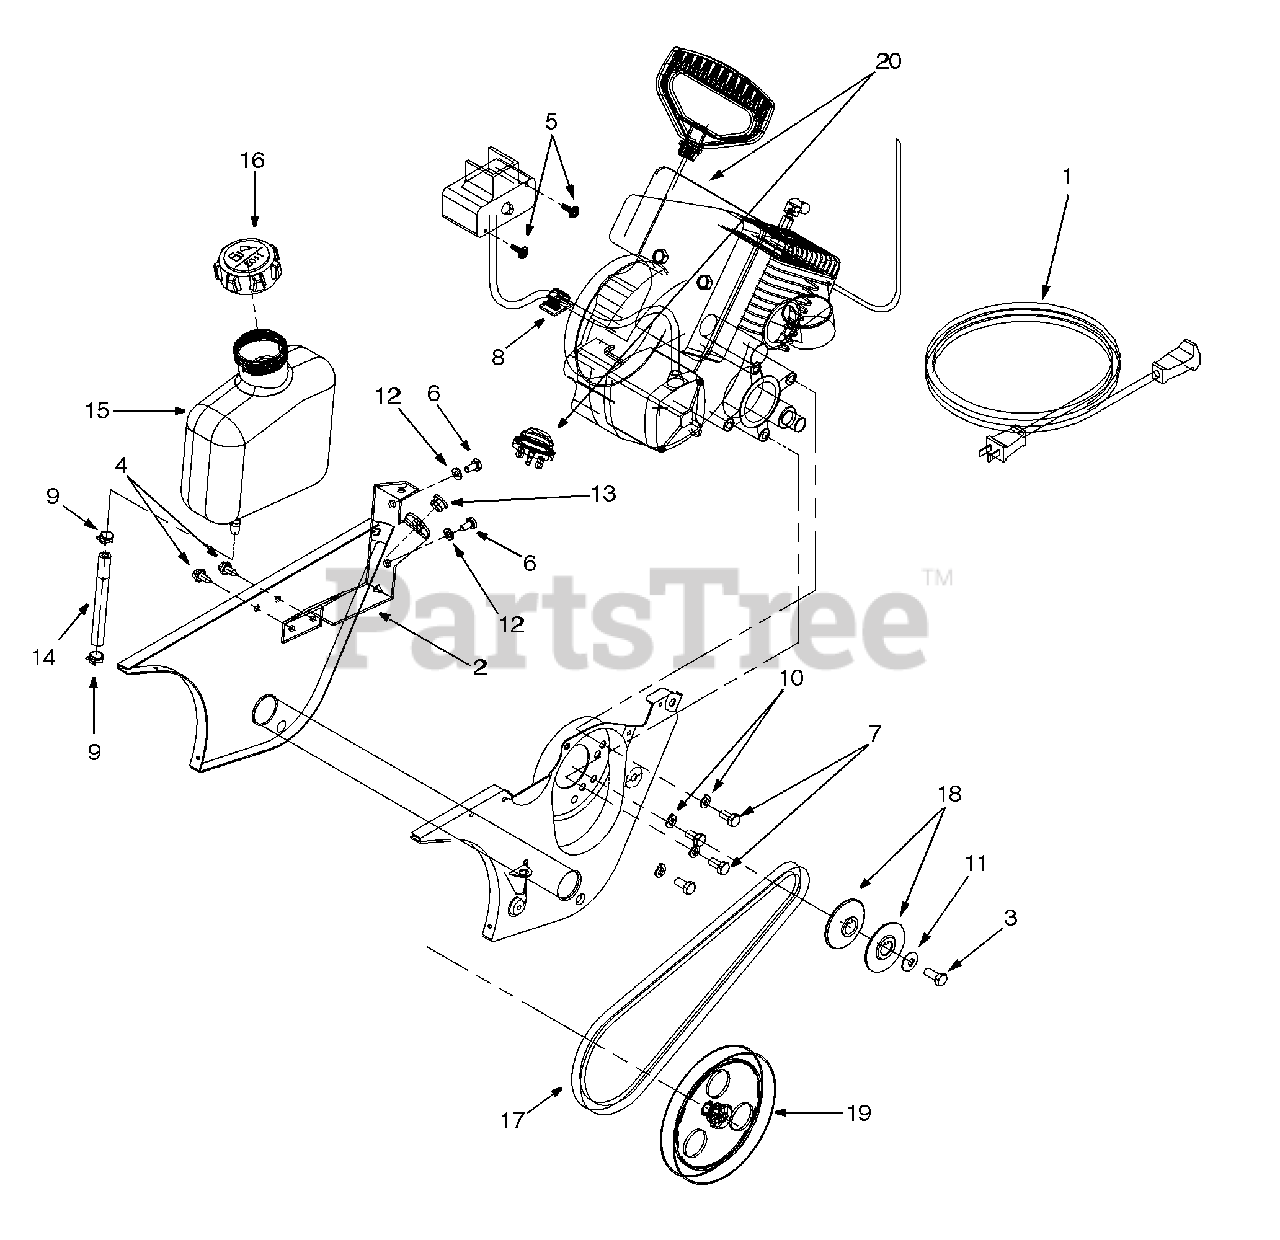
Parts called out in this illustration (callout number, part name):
1	Cord, Extension
4	Screw, Washer
5	Screw, Hex
6	Screw, Hex
7	Screw, Hex Cap
8	Clamp, Mounting
9	Clamp, Hose
10	Washer, Lock
11	Washer, Bell
12	Washer, Lock
13	Bushing
14	Hose, Fuel
15	Tank, Fuel
16	Cap, Fuel
17	V, Belt
18	V-Pulley, Half
